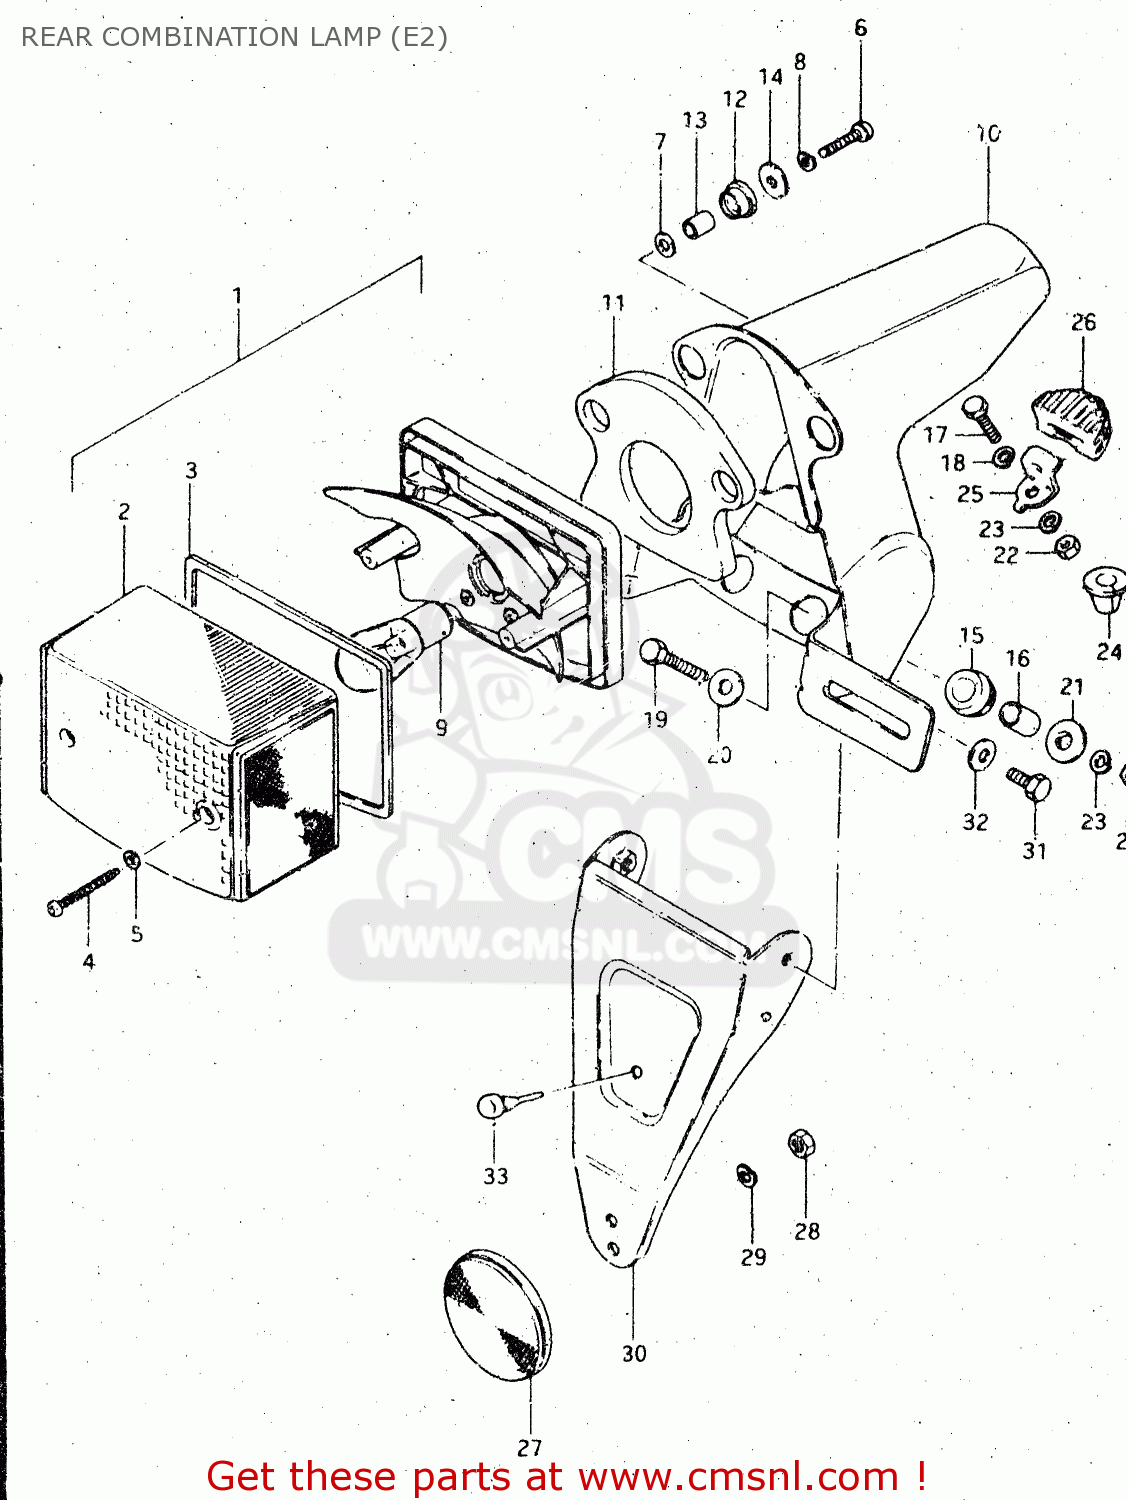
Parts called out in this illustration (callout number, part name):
1	LAMP UNIT, TAIL
2	LENS,RR COMBINATION
3	GASKET (NAS)
4	SCREW
5	GASKET (NAS)
6	SCREW
7	WASHER
8	LOCK WASHER
9	BULB (6V,21/5W)
10	BRACKET ASSY
11	CUSHION,REAR COMBINATION LAMP
12	CUSHION,REAR COMBINATION LAMP
13	SPACER,REAR COMBINATION LAMP
14	WASHER,REAR COMBINATION LAMP
15	CUSHION,REAR COMBINATION LAMP
16	SPACER
17	BOLT
18	LOCK WASHER
19	BOLT
20	WASHER (6.5X20X1.2)
21	WASHER
22	NUT
23	WASHER, LOWER
24	GROMMET
25	PLATE,RR COMBINATION LAMP
26	CUSHION,REAR COMBINATION LAMP
27	REFLEX REFLECTOR,RR
28	NUT
29	LOCK WASHER
30	BRACKET
31	BOLT
32	WASHER
33	CUSHION
